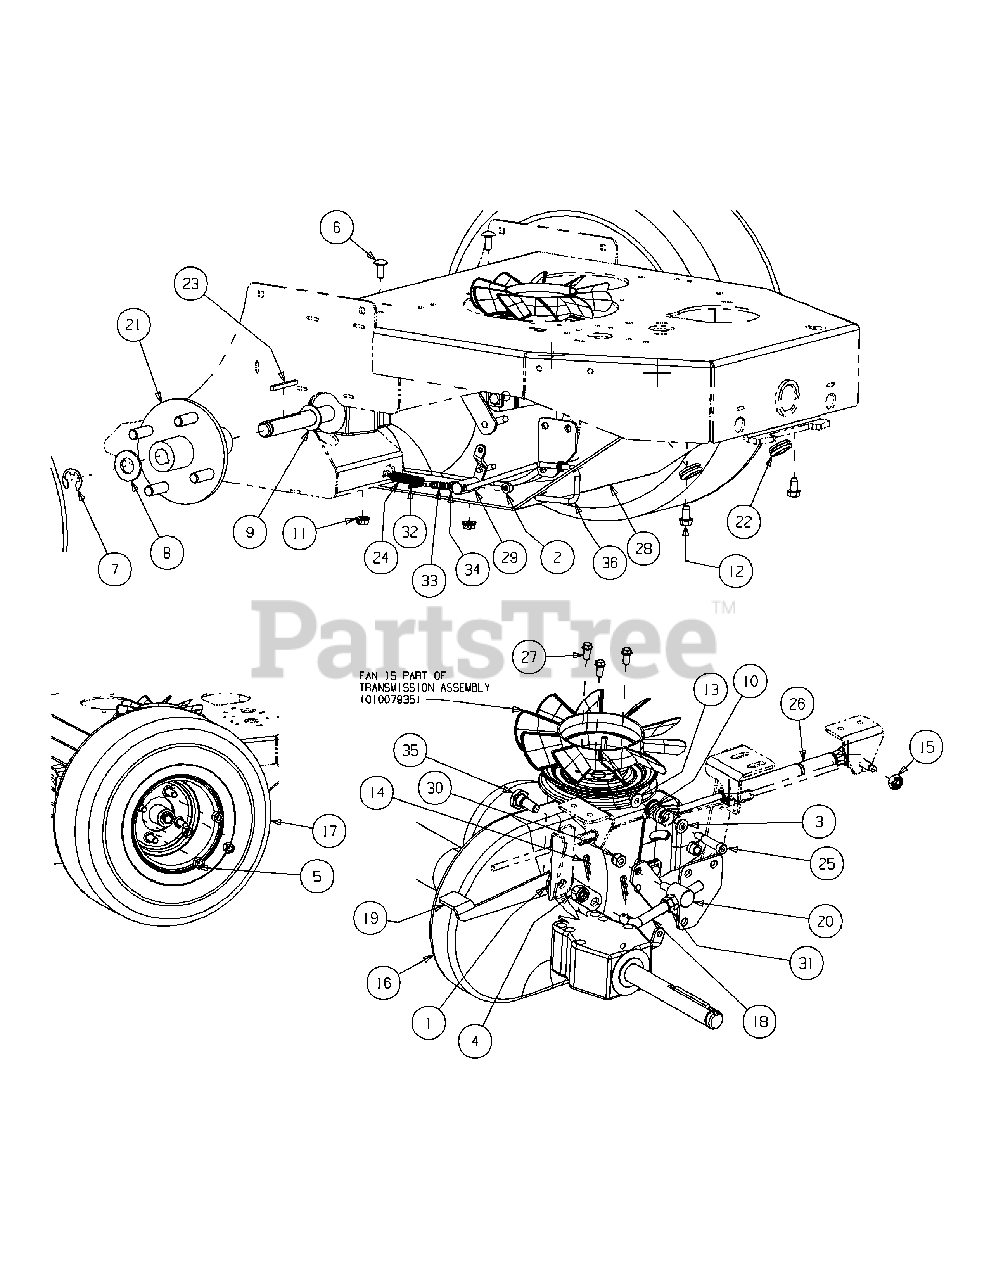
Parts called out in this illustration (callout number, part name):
1	Washer, 1/2
2	Lock Nut w/Nylon Insert
3	Washer, 5/16
4	Nut, 3/8-16
5	Lug Nut, 1/2-20
6	Carriage Bolt, 5/16-18 x .75
8	Washer, .781 ID x 2.00 OD x .105
9	Washer, .06 x .776 x 1.25, SS
10	Washer, 1/4 x .630 x .0515
11	Nut, 5/16-18, Hex Flange Lock
12	Self Tapping Screw, 5/16-18 x .625
13	Nut, 1/4-20
14	Cotter Pin, .072 x 1.12 Long
15	Nut, M8, Top Lock
16	Transmission, Hydro Gear
17	Wheel Assembly, 18 x 6.50-8
18	Brake Lever Rod
19	Brake Lever
20	Pivot Brake Joint
21	Wheel Hub Assembly
22	Rubber Grommet
23	Key, 3/16 x 3/16 x 2
24	Extension Spring
25	Shoulder Bolt, 5/16 x 1.00
26	Damper Assembly
27	Self Tapping Screw, 1/4-20 x .75
28	Transmission Skid Plate
29	Ferule, .625 x .25
30	Nut, 5/16-18, Nylock
31	Hex Jam Nut, 3/8-24
32	Cotter Pin, 3/32 x .750 Long
33	Spring, 0.340 x 1.0 LG
34	Washer, .265 x .562 x .025
35	Shoulder Bolt, .500 x .270, 3/8-16
36	Bypass Rod
